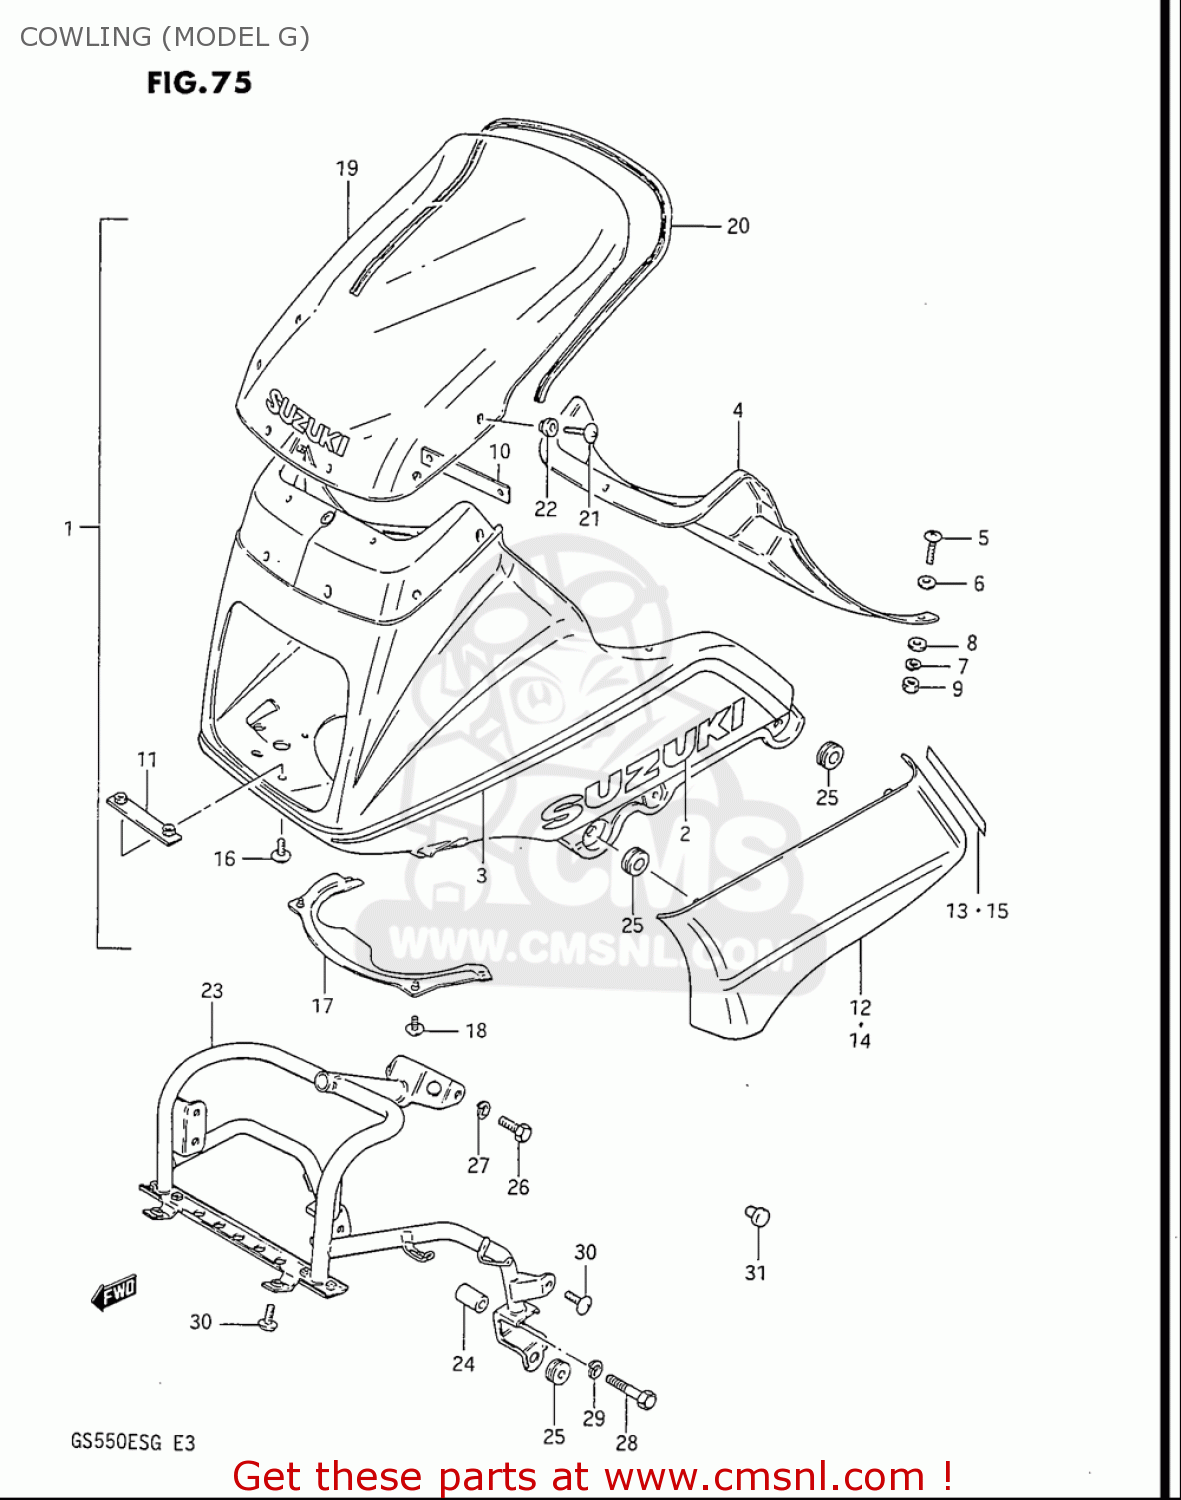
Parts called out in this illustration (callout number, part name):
1	BODY ASSEMBLY,COWLING
2	EMBLEM
5	SCREW
6	WASHER
7	LOCK,WASHER
8	WASHER
9	NUT
12	COVER,COWLING,RIGHT
16	SCREW
18	SCREW
19	WINDOW,COWLING
20	MOLD,COWLING
21	SCREW
22	CUSHION
24	SPACER (8.2X12.5X23.5)
25	CUSHION
26	BOLT
27	WASHER,LOCK
28	BOLT
29	WASHER,LOCK
30	SCREW
31	CAP
